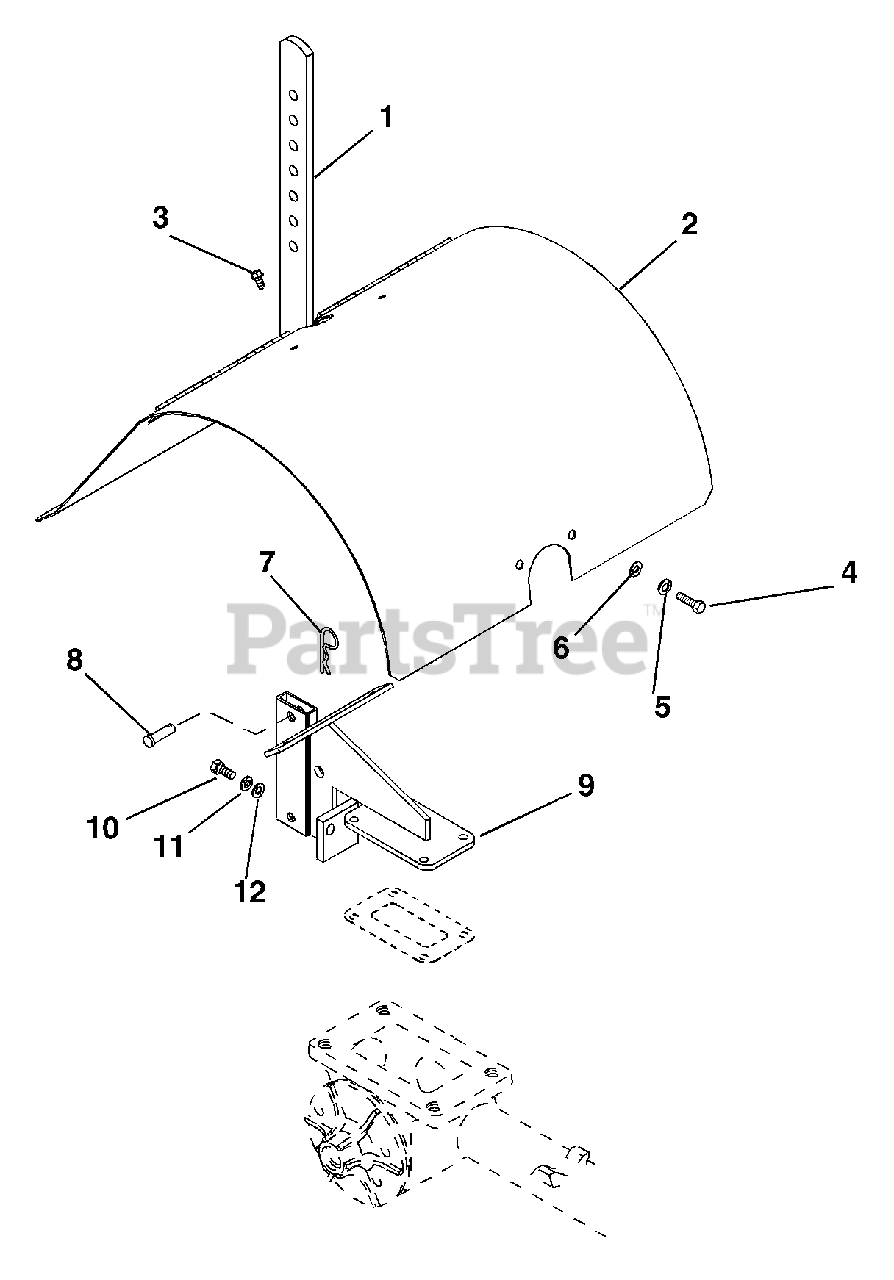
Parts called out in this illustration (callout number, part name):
1	DEPTH STICK
2	TINE HOOD W/ DECALS
3	@SCR-TAP .25-20X.50 HWH TR YWZ
4	@BLT-HEX .31-18X.50 GR5 YWZC
5	WSHR-LOCK INT .31 YWZC
6	@WSHR-FL-STL.312X.734X.065 YWZ
7	PIN-HAIR-EXT .12X.31X2.37 YWZC
8	PIN-CLEV .38 X 1.06
9	DEPTH STICK HOLDER
10	@BLT-HEX .31-18X1.00 GR5 YWZC
11	@WSHR-LK .31X.078 REG YWZC
12	@WSHR-FL-STL.344X.688X.065YWZC
